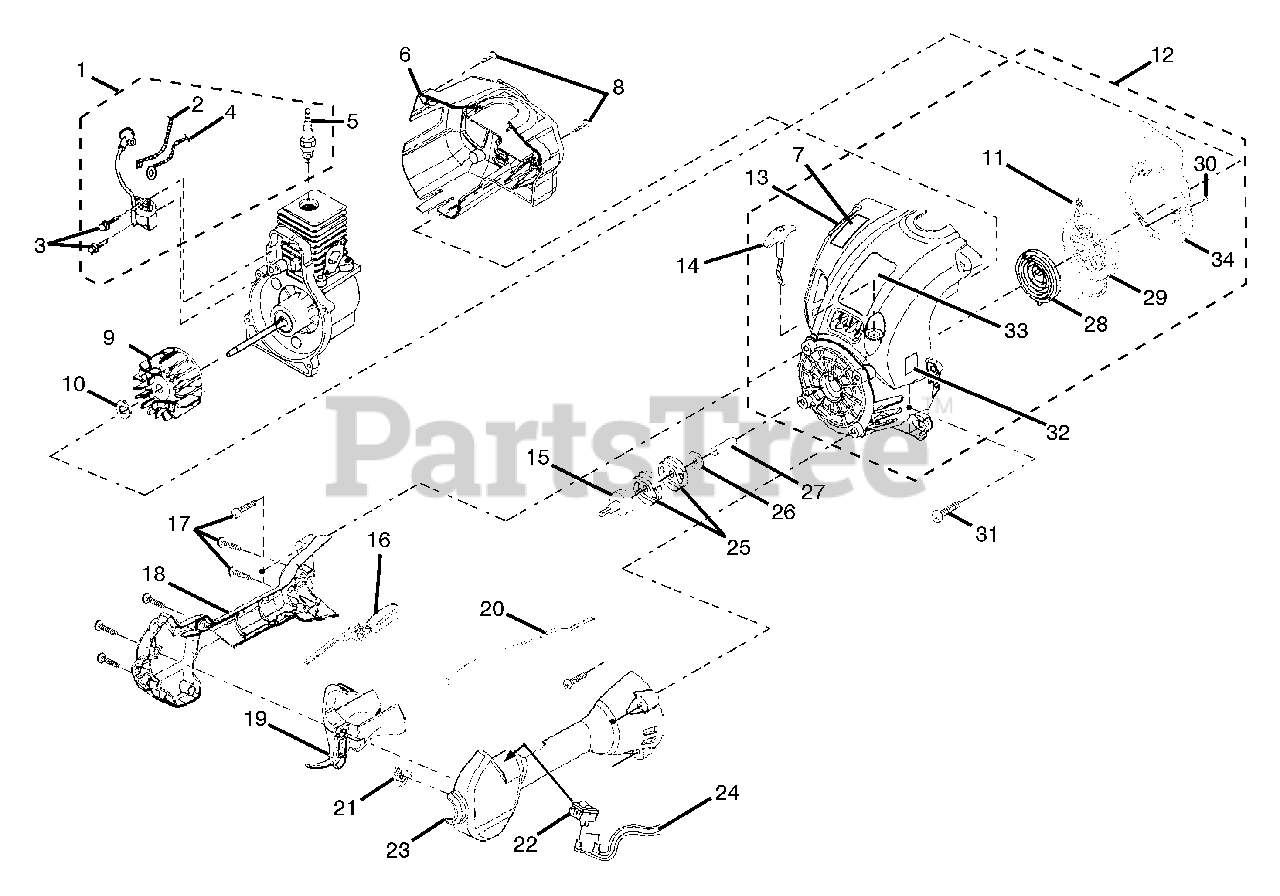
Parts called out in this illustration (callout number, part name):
1	IGNITION KIT
2	ELECTRICAL LEAD
4	ELECTRICAL LEAD
5	SPARK PLUG
6	REAR COVER
7	DECAL, HOMELITE
8	SCREW (10-14 x 7/8")
9	ROTOR AND PAWL ASSEMBLY
11	STARTER ROPE (42 in)
12	STARTER ASSEMBLY
13	STARTER HOUSING AND EYELET
14	STARTER GRIP
15	DRUM AND CONNECTOR
16	INTERLOCK TRIGGER
18	CONTROL HANDLE / RH
19	TRIGGER
20	THROTTLE CABLE
23	CONTROL HANDLE / LH
24	ELECTRICAL LEADS
25	CLUTCH DISK ( ST185 & ST385 )
26	WASHER
27	SPACER
28	SPRING & CONTAINER
29	STARTER PULLEY
32	DECAL, NOISE
33	DECAL, MODEL
34	AIR BAFFLE PLATE
